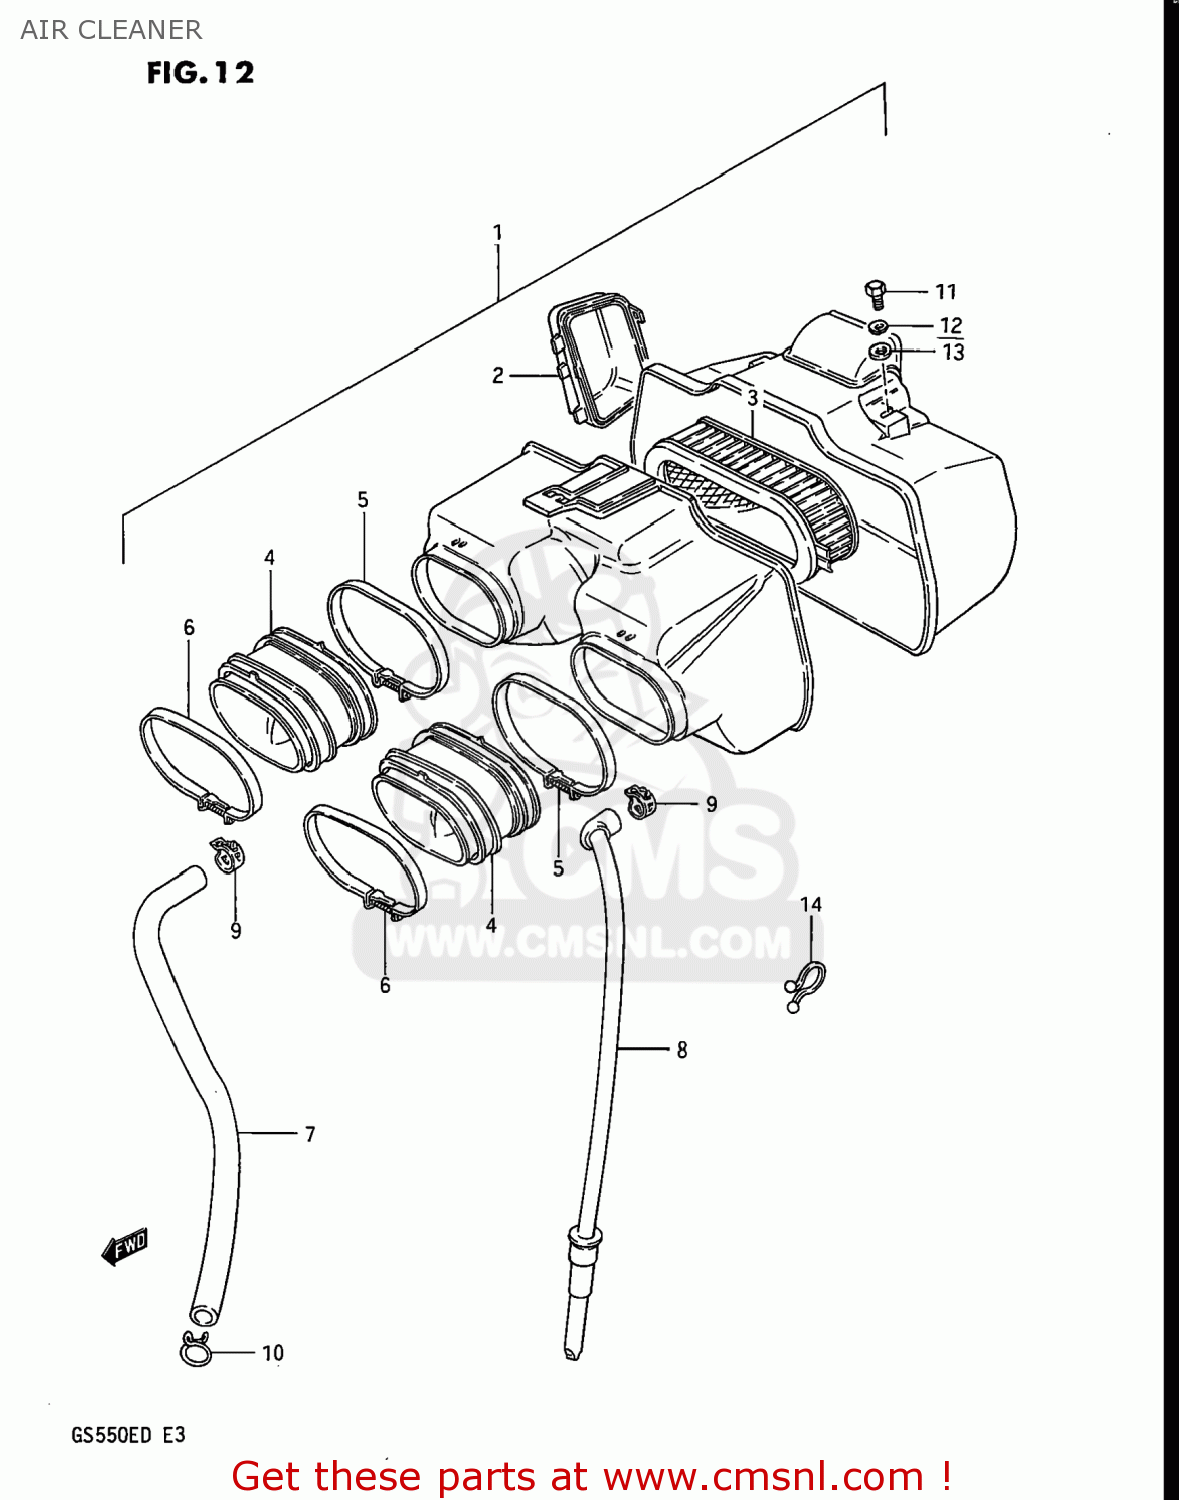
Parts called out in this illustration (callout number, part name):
1	CLEANER ASSEMBLY,AIR
2	CAP,AIR CLEANER
3	FILTER,AIR CLEANER
4	TUBE,AIR CLEANER OUTLET
5	CLAMP
6	CLAMP
7	TUBE,BREATHER
8	DRAIN TUBE
9	CLIP
10	CLIP,BREATHER TUBE
11	BOLT, UPPER
12	LOCK WASHER
13	WASHER
14	CLIP(ID:16)
